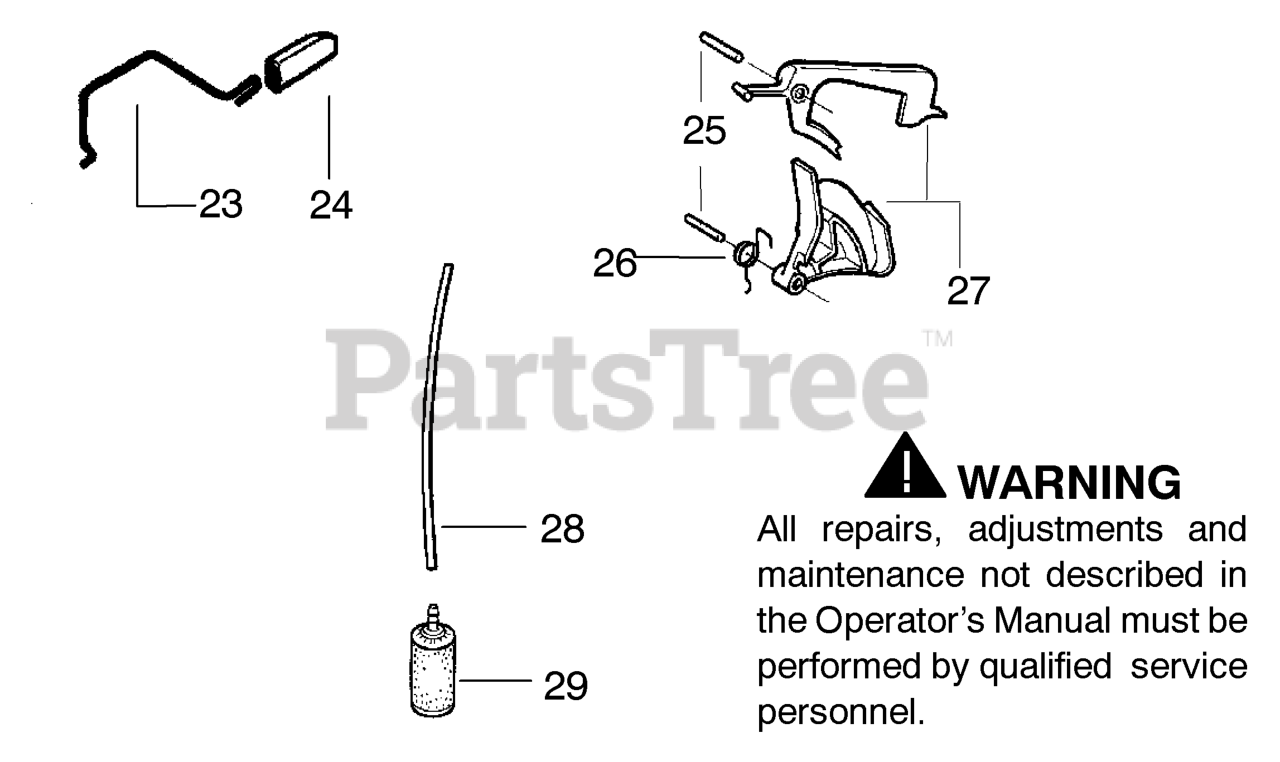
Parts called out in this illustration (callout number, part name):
23	THROTTLE SHAFT 36/41
24	THROTTLE ACTUATOR 36/41
25	PIN,TRIGGER 36/41
26	TRIGGER SPRING 36/41
27	THROTTLE TRIGGER-KIT
28	HOSE. FUEL
29	FUEL PICK-UP
